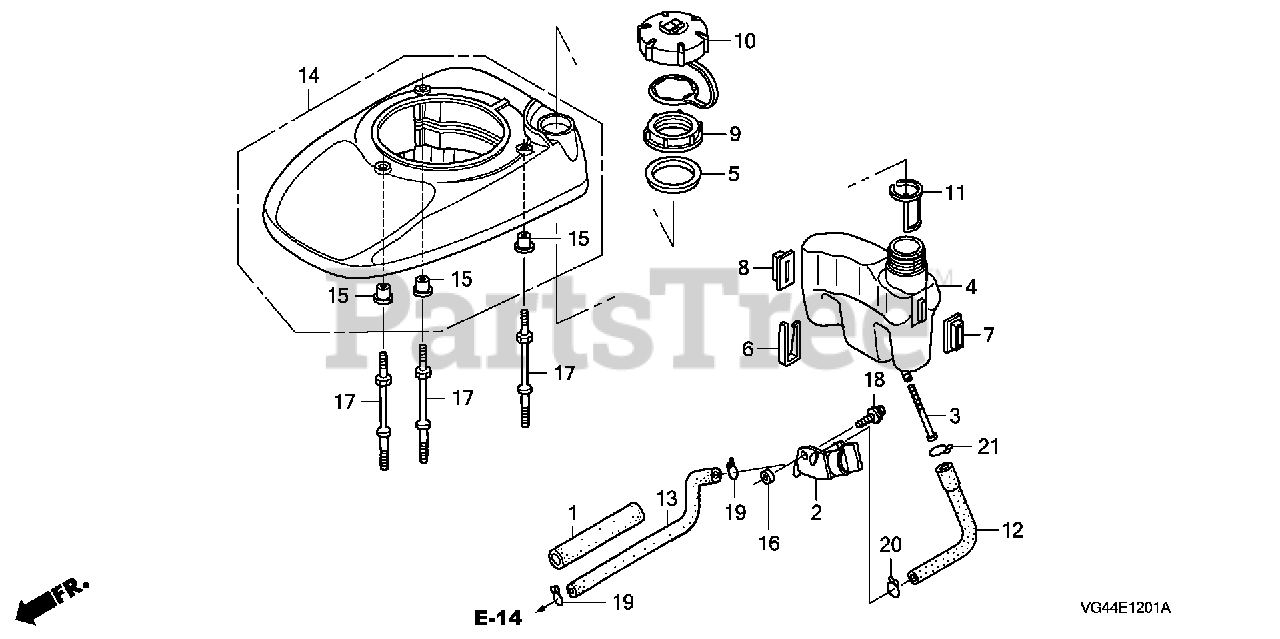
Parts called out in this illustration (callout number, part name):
1	RUBBER, SUPPORTER (107MM)
2	PETCOCK ASSY.
3	FILTER, FUEL
4	TANK, FUEL
5	SEAL, FUEL FILLER NECK
6	CLIP, TANK MOUNTING
7	RUBBER A, TANK MOUNTING
8	RUBBER B, TANK MOUNTING
9	NUT, TANK MOUNTING
10	CAP ASSY., FUEL TANK
11	GAUGE, FUEL LEVEL
12	TUBE, FUEL TANK
13	TUBE, FUEL
14	COVER, FAN *R280* (POWER RED)
15	COLLAR, FAN COVER
16	COLLAR, FR. TURN SIGNAL
17	BOLT, STUD (H=42.5MM)
18	SCREW-WASHER (5X10)
19	CLIP, TUBE (B8)
20	CLIP, TUBE (B10)
21	CLIP, TUBE (C11)
